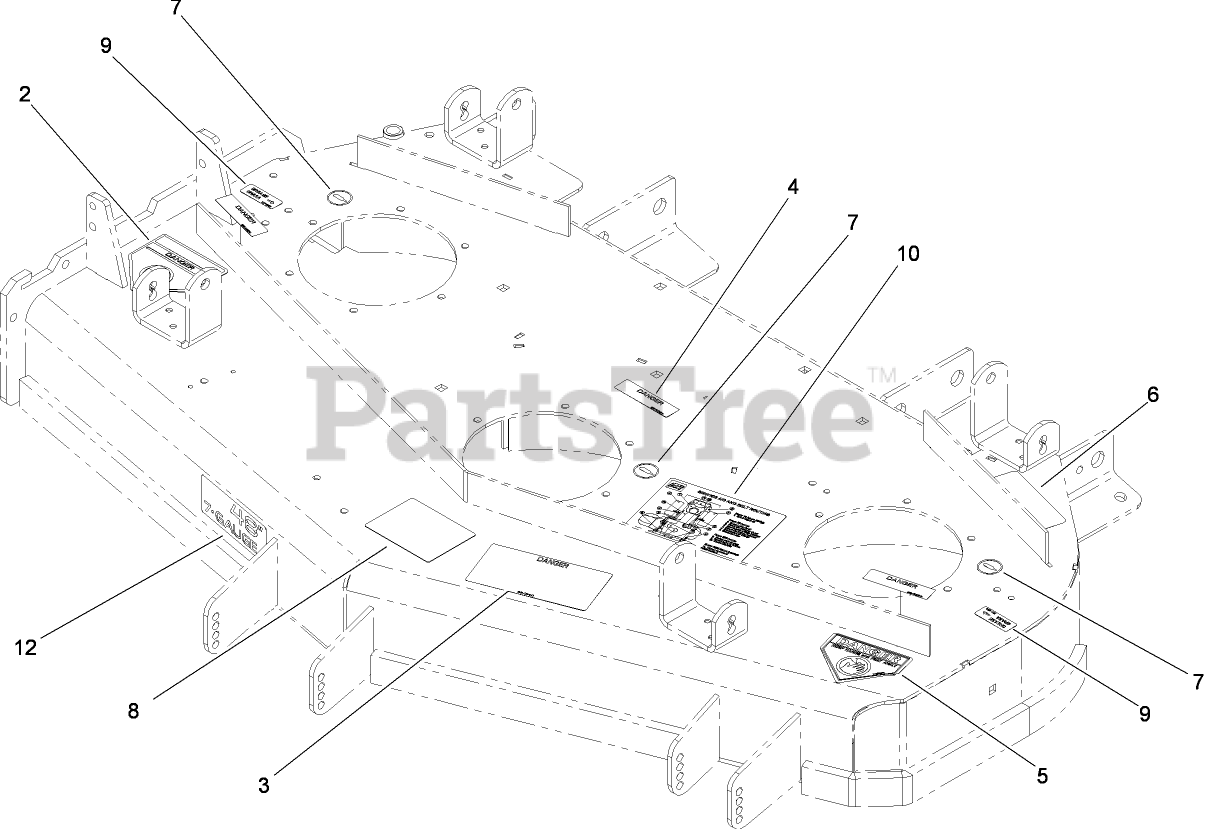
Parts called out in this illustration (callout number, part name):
2	DECAL-DANGER
3	DECAL-DANGER, THROWN OBJECT
4	DECAL-COVER, MISSING
5	DECAL-DANGER
6	DECAL-TORQUE
7	DECAL-GREASE
8	DECAL-SCALP, ANTI
9	Decal-Grease
10	DECAL-AID, SERVICE
